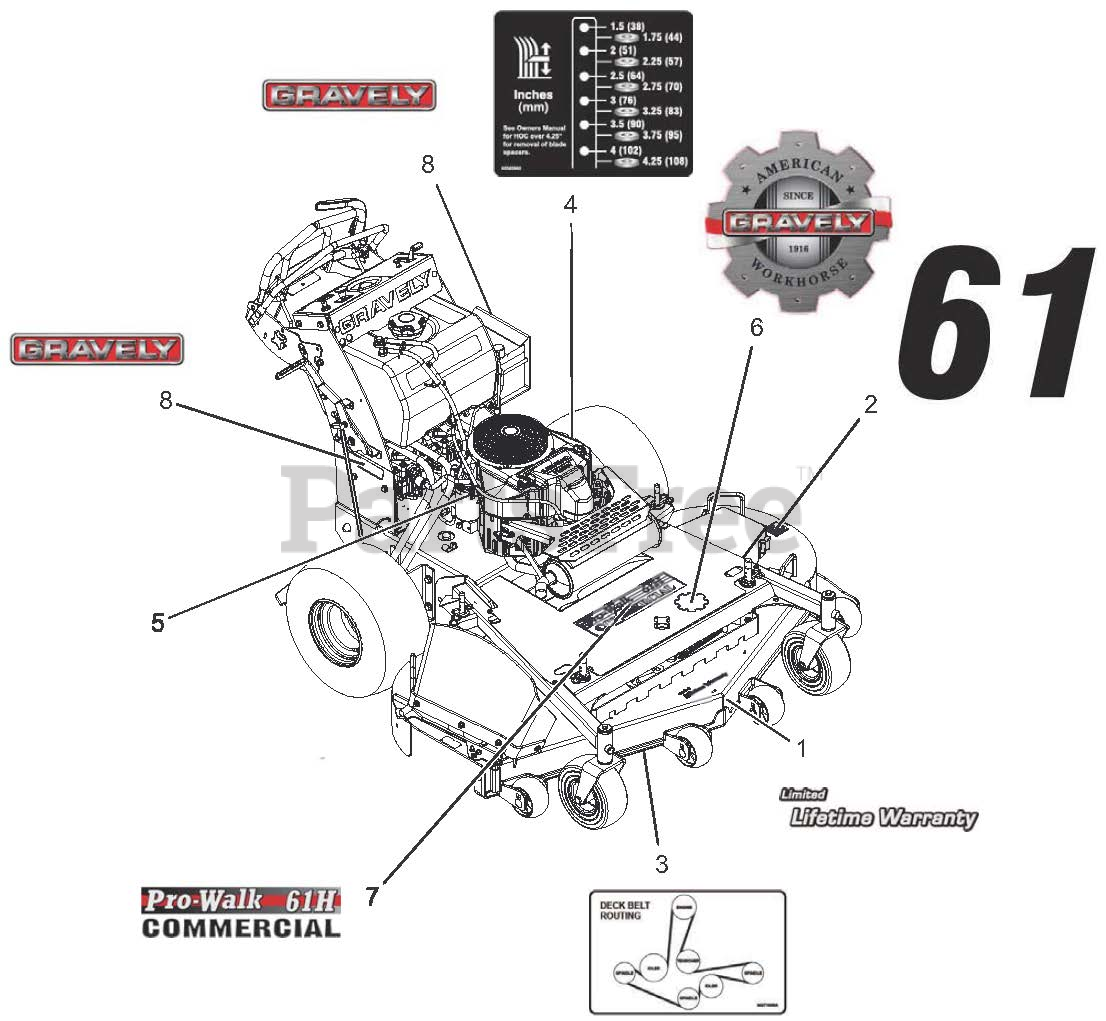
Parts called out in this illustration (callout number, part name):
1	DECAL, LIMITED LIFETIME WARRANTY REV
2	DECAL, 61"
3	DECAL, BELT ROUTING
4	DECAL, PRO WALK HOC A
5	DECAL, PUMP BELT ROUTING
6	DECAL, GRAVELY HERITAGE-LARGE
7	DECAL, PROWALK 61H
8	DECAL, 6.5" GRAVELY LOGO
